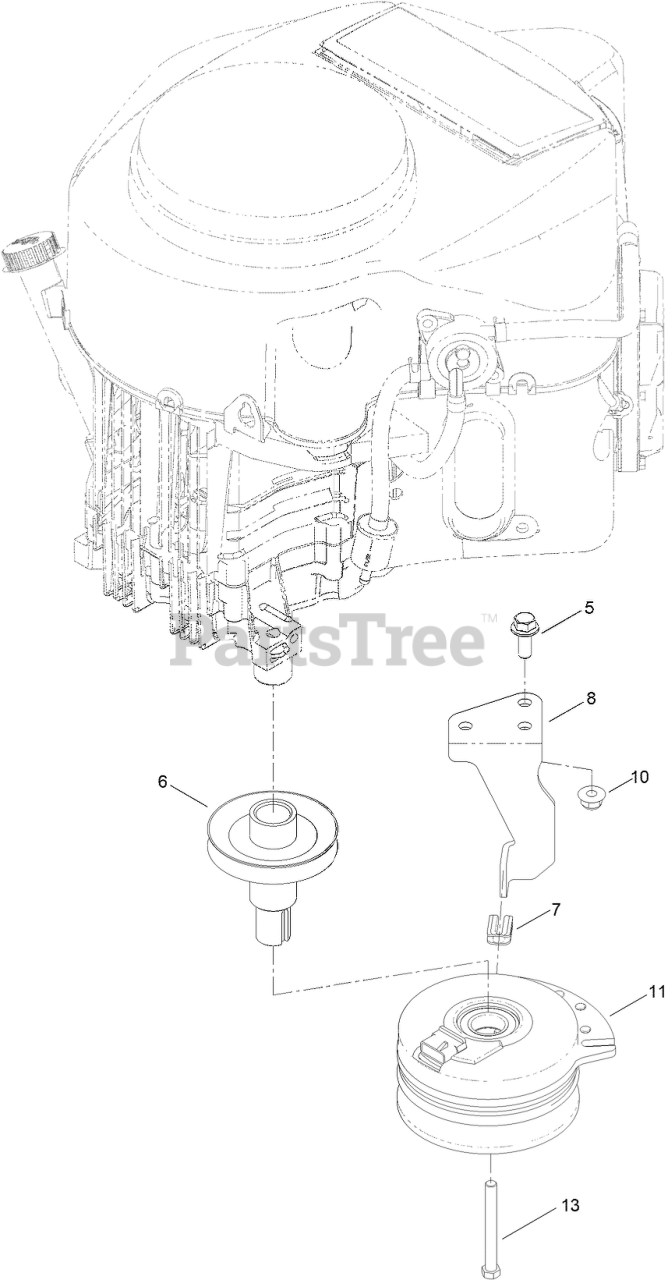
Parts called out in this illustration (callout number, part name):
5	SCREW-HHF
6	PULLEY-ENGINE
7	ISOLATOR-CLUTCH
8	STOP-CLUTCH
10	NUT-HF, NI
11	CLUTCH-ELECTRIC
13	SCREW-HH
